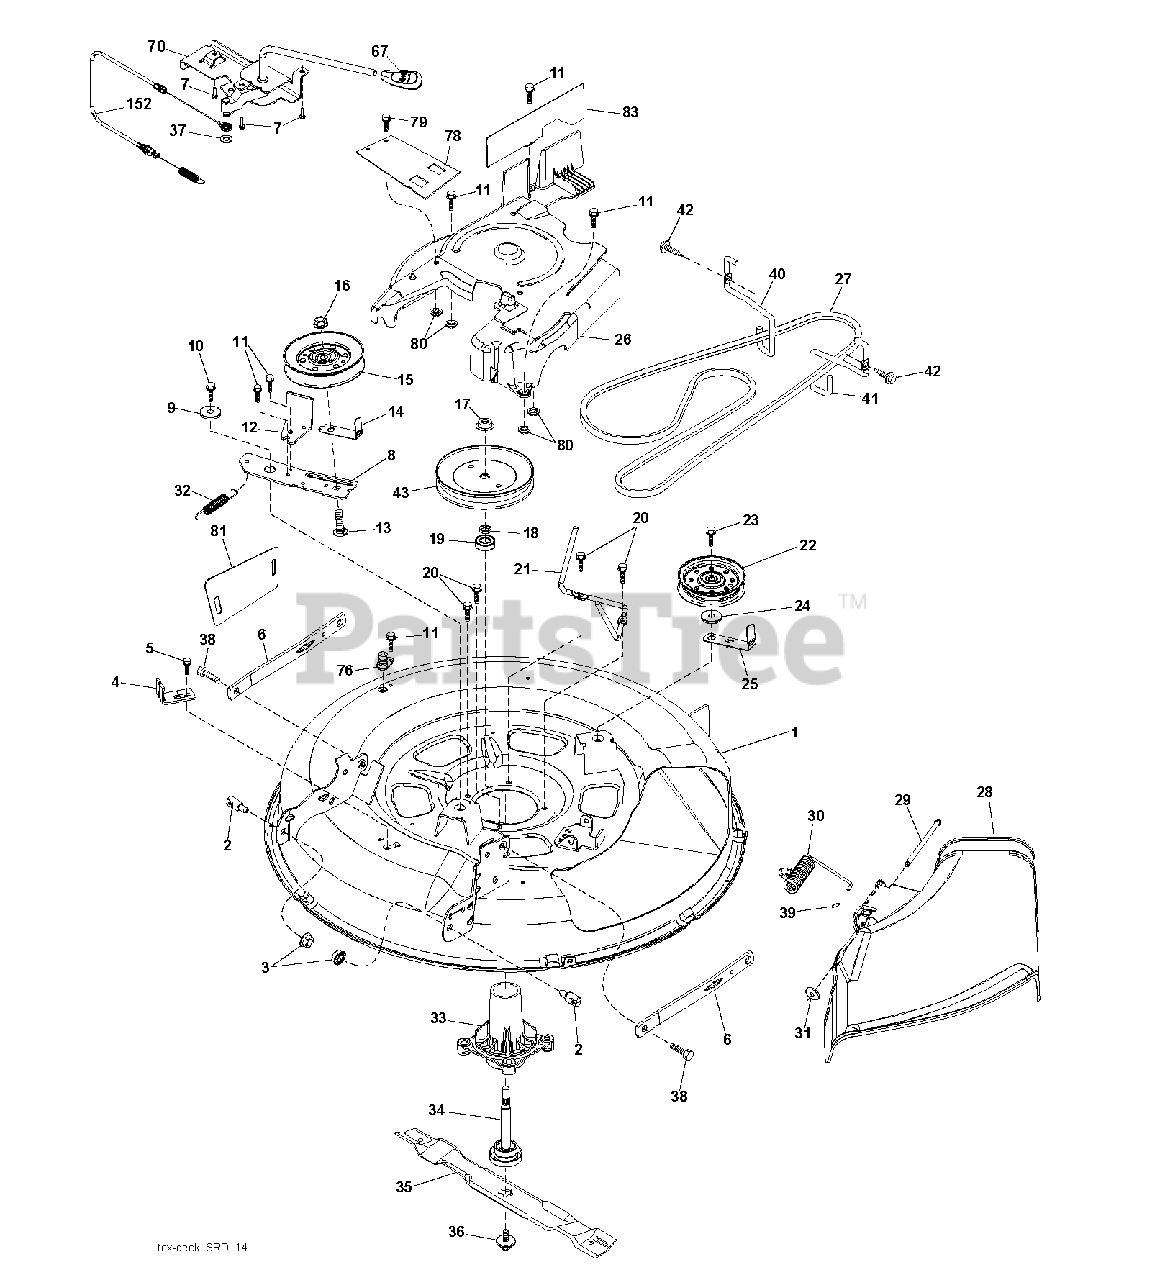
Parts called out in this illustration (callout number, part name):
2	STUD.FASTNER.W/ANTI-ROTATE
3	NUT LOCK HEX FLANGE 5/16-18
5	BOLT.5/16HEX.WHS.HD
6	ARMS.SUSP.MOWER.REAR.SRD
7	SCREW.#10 X 0.750.BOS THREAD
9	SPACER.RETAINER
10	SCREW 3/8-16X1
11	SCREW.1/4-20X5/8
12	ARM BRAKE MOWER RH
13	BOLT.3/8-16X1.50
14	KEEPER, BELT IDLER
15	PULLEY.IDLER.4.25
16	NUT LOCK FLG 3/8-16 UNC
17	NUT.FLANGE.LOCK.TOP
18	WASHER.SPACER.MANDREL
20	SCREW, WASHER HEAD
22	PULLEY.IDLER.FLAT.UNPLATED
23	SCREW LT
27	V-BELT.DRIVE.MOWER.30"
28	SHIELD.DEFLECT.MWR.30S.BLACK
30	SPRING.TORSION.DEFLECT
31	NUT PUSH M
32	SPRING RETURN
33	HOUSING MANDREL
34	SHAFT.ASM.MDRL.N/GREASE.38
35	BLADE, MULCH.LRV30
36	BOLT.WASHER.ASM.7/16-2
38	BOLT.SHOULDER
39	CAP-SLEEVE LT
42	SCREW, 3/8-16X3/4
43	PULLEY, MANDREL 6.5 PD
67	HANDLE.CLUTCH.CABLE.LT
70	CLUTCH.ASM.MANUAL.LT.PRED
76	PORT.WASHOUT
79	SCREW.HI-LO.CONSOLE
80	PALNUT 1/4
152	CABLE.CLUTCH.MANUAL.
